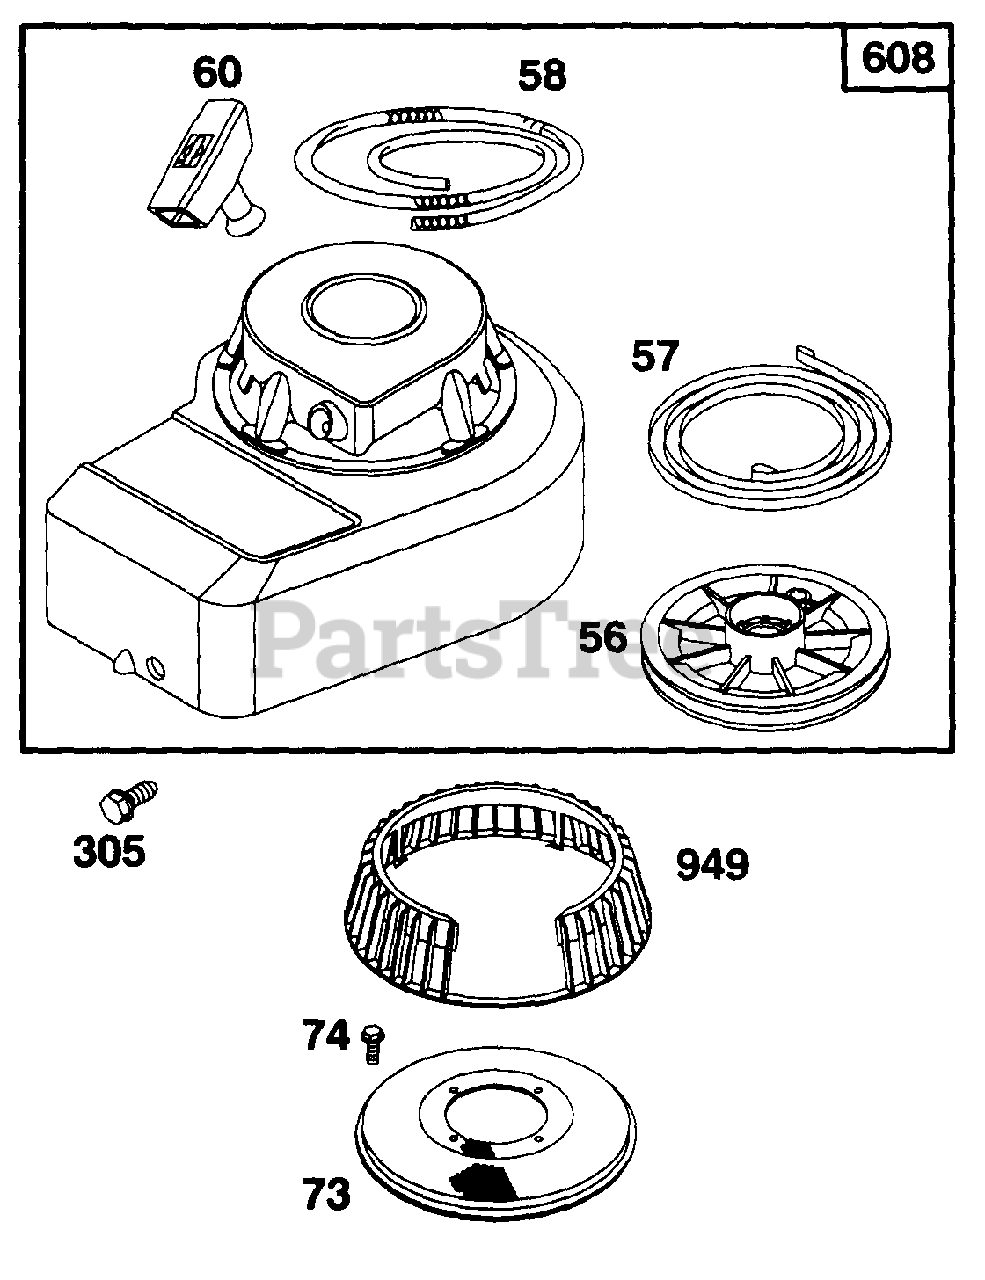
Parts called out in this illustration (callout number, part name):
56	Pulley-Starter
57	Spring-Rewind Starter
58	Rope-Starter
60	Grip-Starter Rope
73	Screen-Rotating
74	Screw-Sem
305	Screw-Hex. Head
608	Starter-Rewind
949	Guard-Finger
